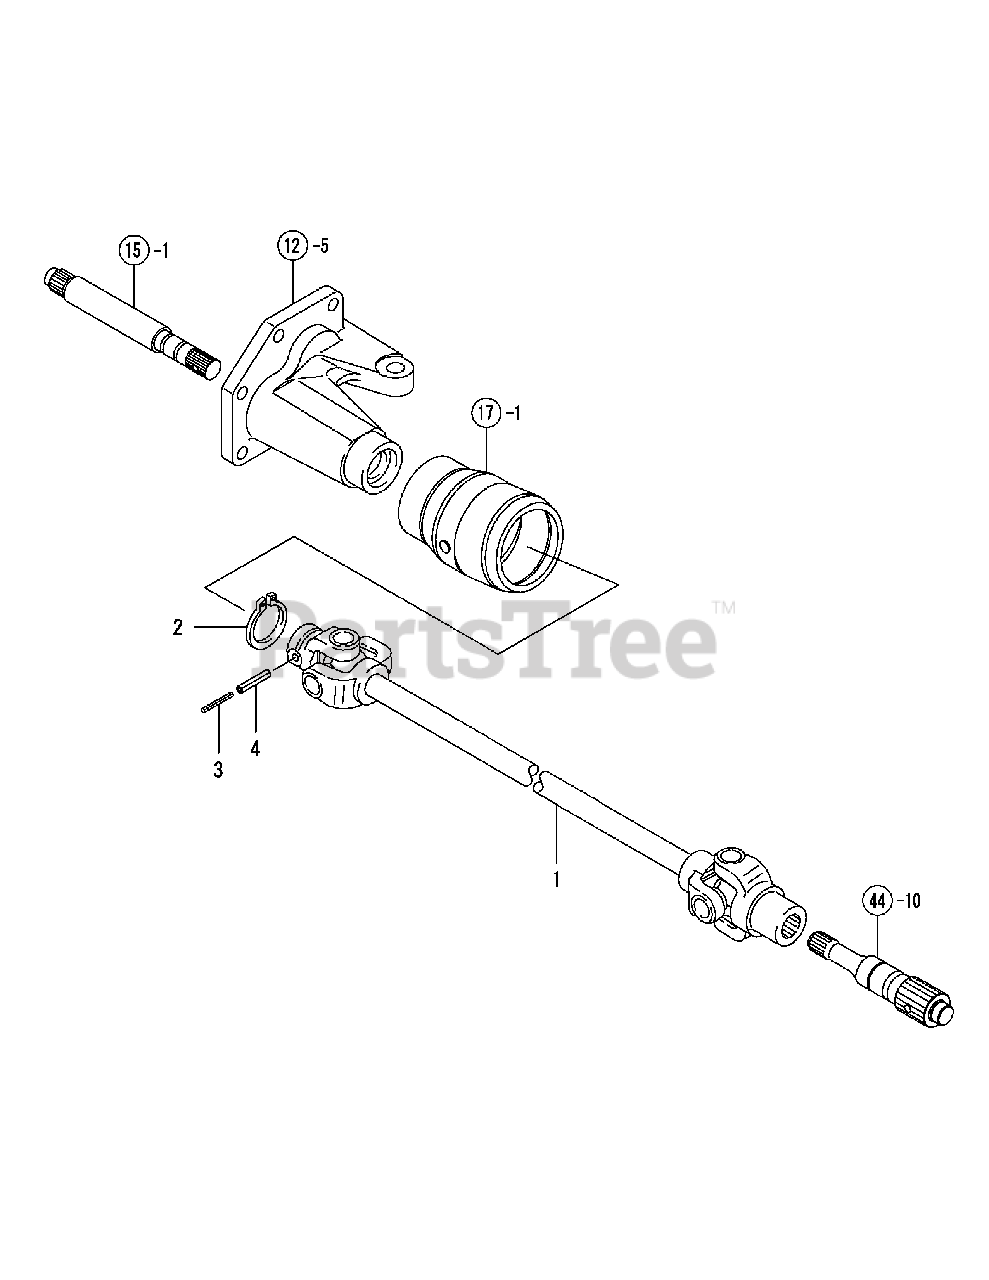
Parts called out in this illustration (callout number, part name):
1	Shaft Assy,Propeller
3	Spring Pin 3.5X32
4	Spring Pin 6X32
